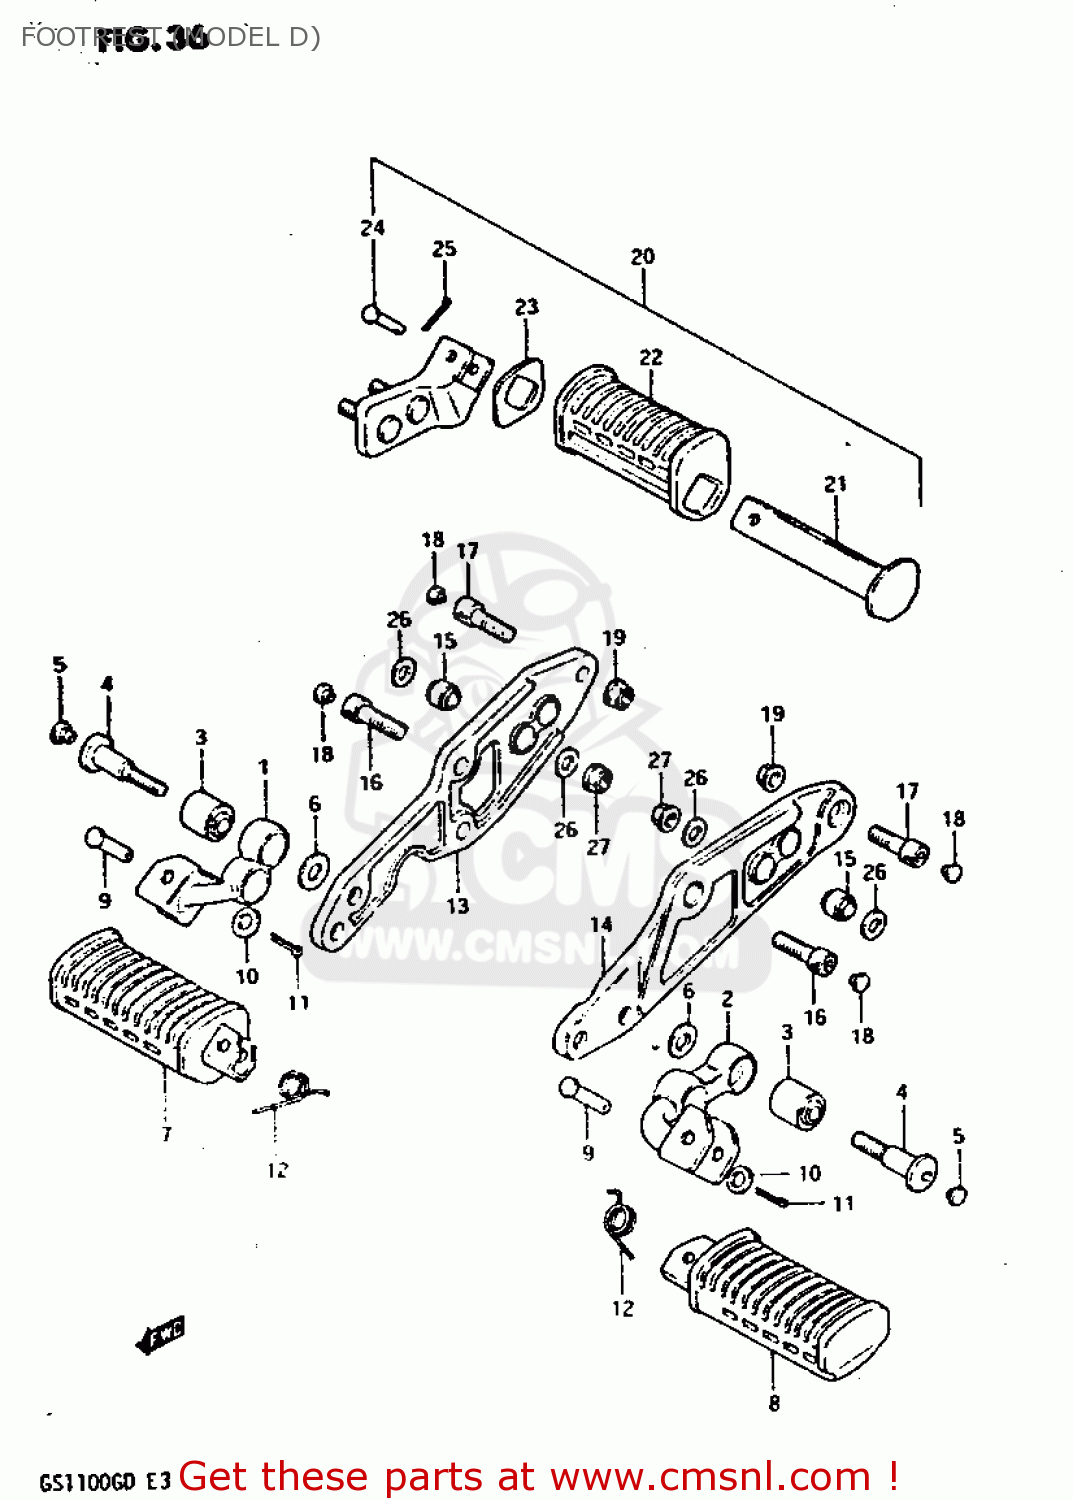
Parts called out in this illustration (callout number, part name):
1	BAR,FRONT FOOTREST,RIGHT
2	BAR,FRONT FOOTREST,LEFT
3	BUSH
4	BOLT(10X50)
5	CAP
6	WASHER (10X18X3.2)
7	RUBBER,FRONT FOOTREST
8	FOOTREST
9	PIN
10	WASHER
11	PIN 20X20
12	SPRING
13	BRACKET,MUFFLER,RIGHT
14	BRACKET,MUFFLER,LEFT
15	BUSH
16	BOLT
17	BOLT, (10X30)
18	CAP
19	NUT
20	FOOTREST ASSEMBLY,REAR,LEFT
21	BAR,REAR FOOTREST
22	RUBBER,RR FOOTREST
23	WASHER,RR FOOTREST RUBBER
24	PIN
25	PIN 20X20
26	WASHER(10.5X20X3.2)
27	NUT
